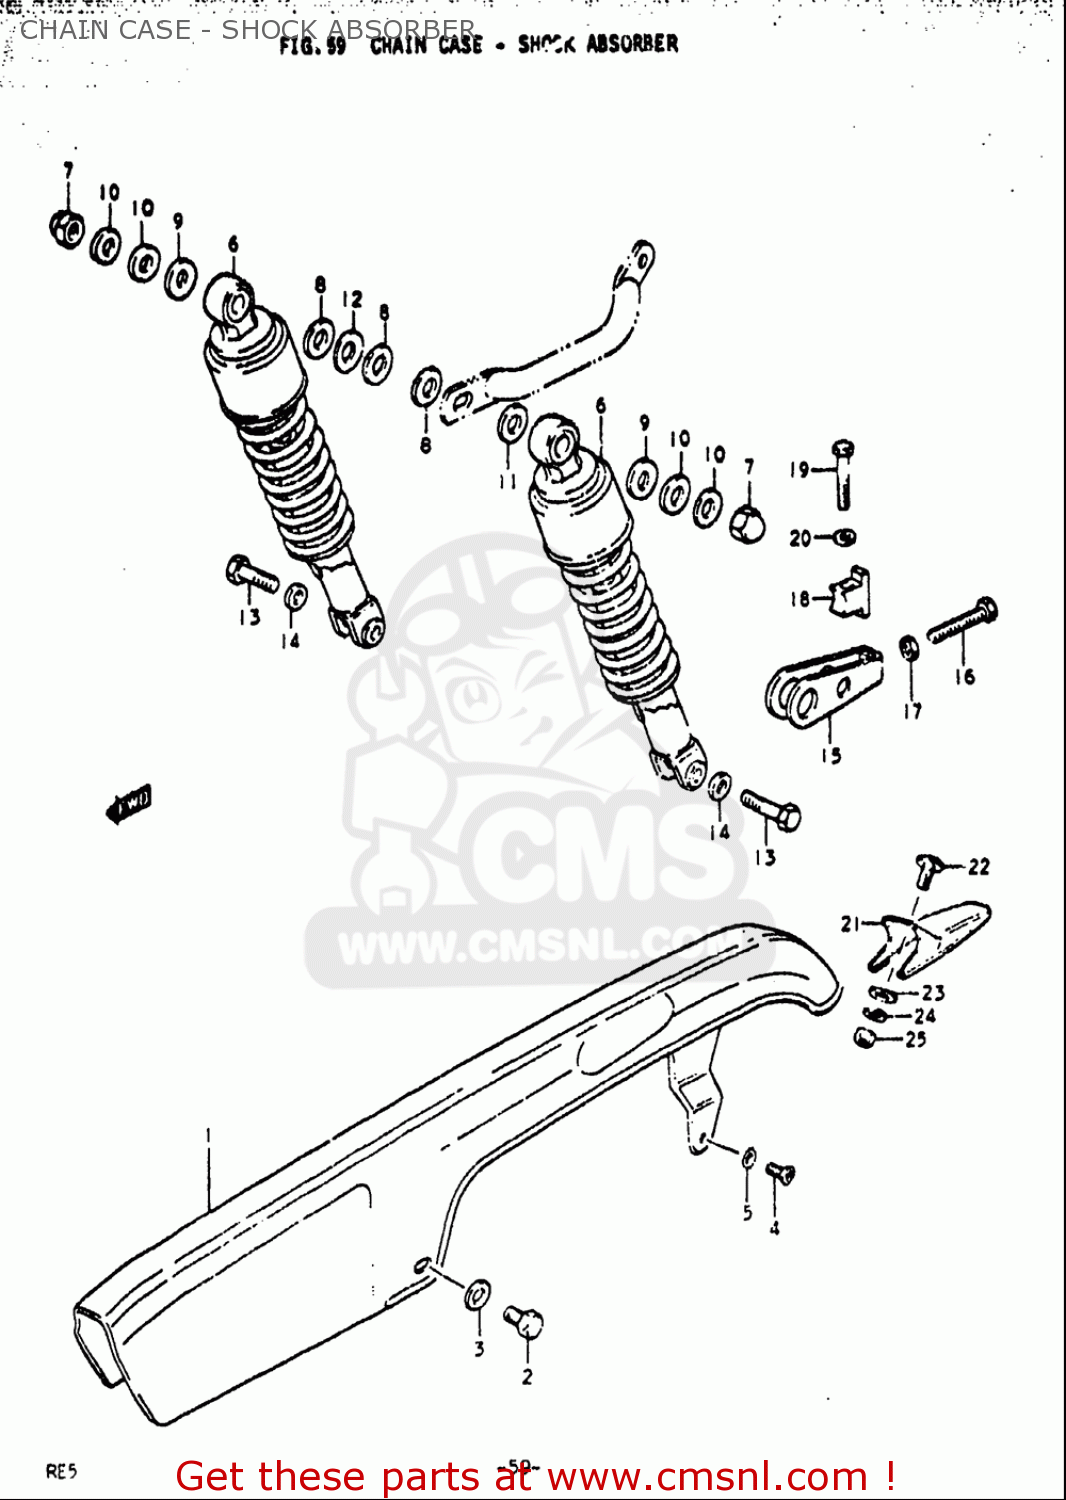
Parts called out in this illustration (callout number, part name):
2	BOLT(6X8)
3	WASHER(6.5X18X1.6)
4	SCREW
5	LOCK WASHER
7	NUT
8	WASHER
9	WASHER(10.5X28X2.3)
10	WASHER (10.5X25X3.2)
11	WASHER(12.5X24X1.6)
12	WASHER(12.5X24X3.2)
13	BOLT(10X38)
14	WASHER
15	ADJUSTER,CHAIN
16	BOLT(8X50)
17	NUT
18	SUPPORTER,CHAIN ADJUST
19	BOLT
20	WASHER
22	SCREW
23	WASHER
24	WASHER,LOCK
25	NUT
